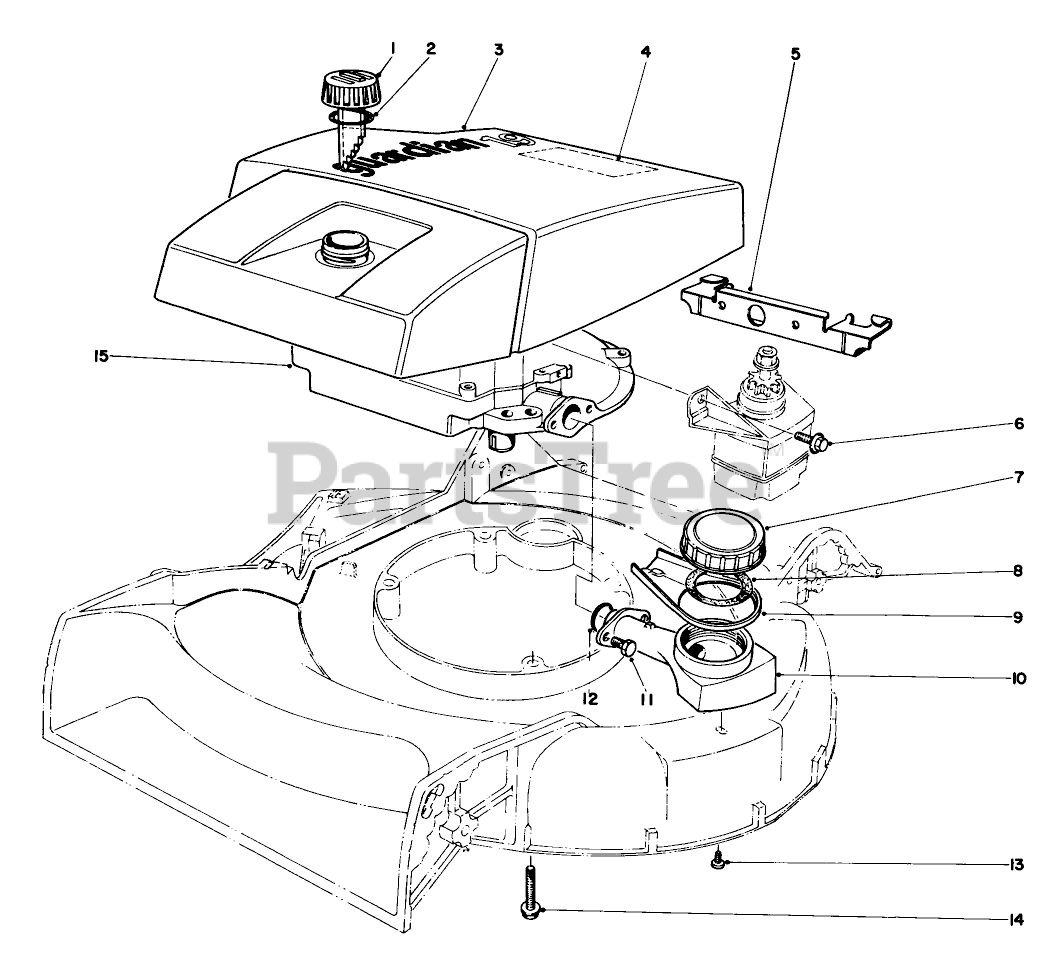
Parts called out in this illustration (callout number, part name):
1	Gas Cap (Incl. Ref. No. 2)
2	Gasket
3	Shroud
4	Decal-Maintenance
5	Shroud Bracket
6	SCREW
7	Oil Gauge Cap
8	VISUAL OILER GASKET
9	Spout
10	Oil Gauge
11	SCREW-HH
12	O RING
13	Screw
14	3/8-16 X 2-3/4 CAPSCR
15	Engine
